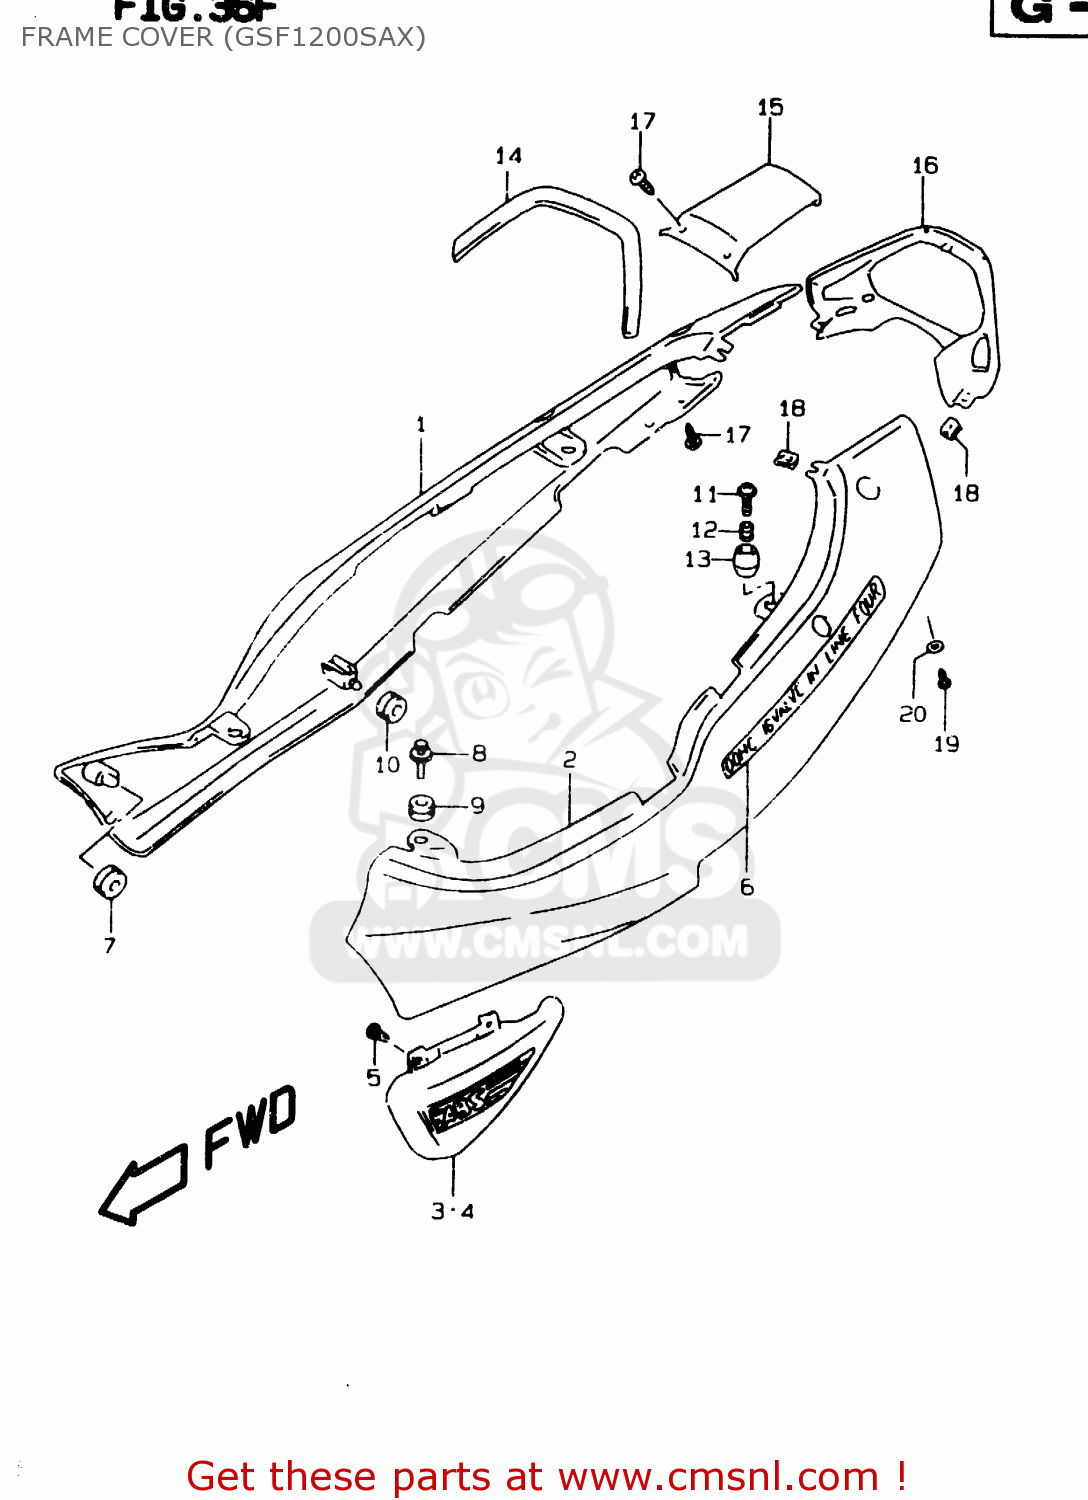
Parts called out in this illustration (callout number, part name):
1	COVER,FRAME,R(MAROON)
2	COVER,FRAME,L(BLACK)
3	COVER,FRAME LWR,R
4	COVER,FRAME LWR,L
5	SCREW
6	EMBLEM,FRAME COVER
7	CUSHION,FRAME COVER FR
8	CLIP
9	CUSHION
10	CUSHION
11	SCREW(6X20)
12	SPACER(6.5X10X9.4)
13	CUSHION
14	CUSHION,FRAME COVER UPR
15	COVER,FRAME CTR
16	COVER,FRAME RR
17	SCREW
18	NUT
19	SCREW
20	WASHER(6.3X16X1.5)
